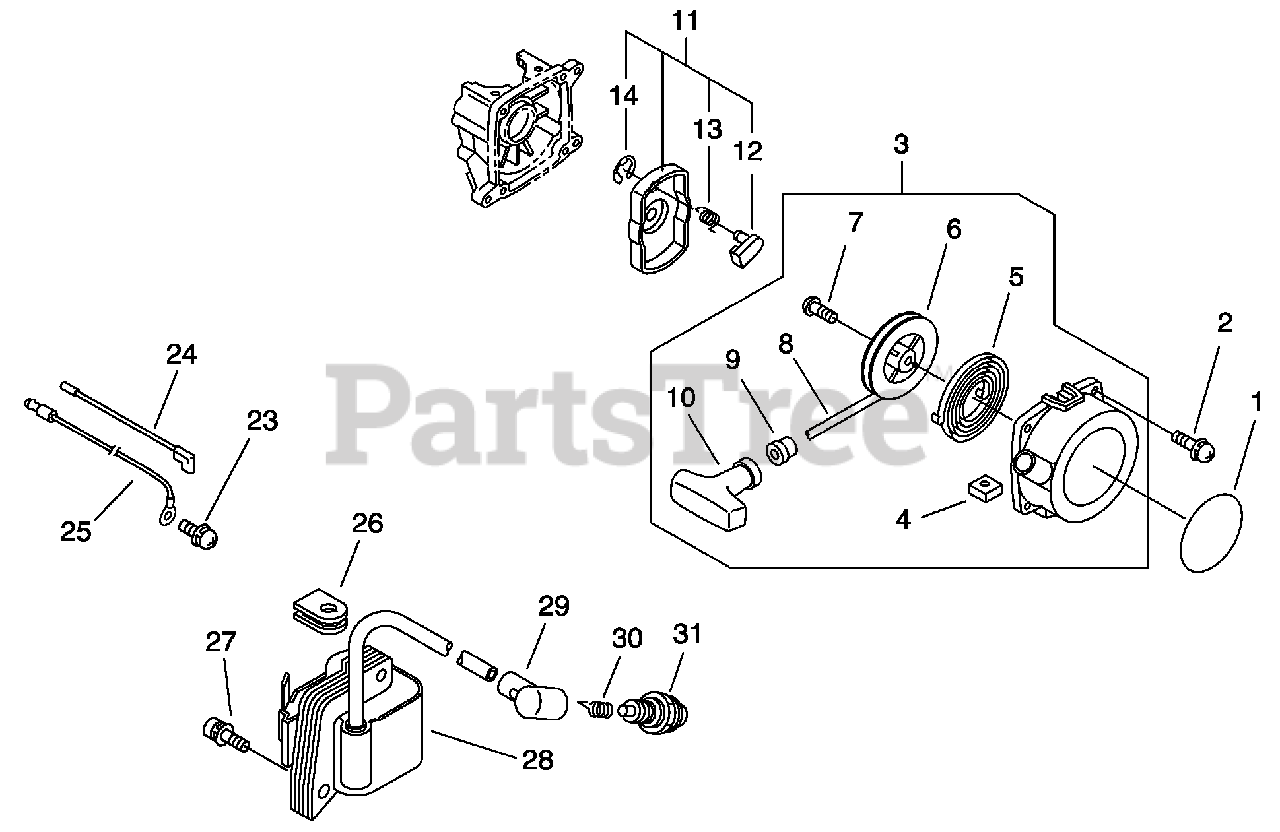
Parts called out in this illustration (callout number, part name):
1	LABEL, RECOIL STARTER
2	BOLT 4×14
3	STARTER ASSY, RECOIL
4	NUT M5
5	SPRING, RECOIL
6	REEL, ROPE
7	SCREW
8	ROPE, STARTER 3×800
9	GUIDE, ROPE
10	GRIP, STARTER
11	PAWL ASSY, STARTER
12	PAWL, STARTER
13	SPRING, RETURN
14	E-RING 4
23	SCREW 5×10
24	LEAD - IGNITION 145 MM
25	LEAD - GROUND
27	BOLT 5×22
28	COIL, IGNITION
29	CAP, SPARK PLUG
30	TERMINAL, SPARK PLUG
31	SPARK PLUG - BPM7A
